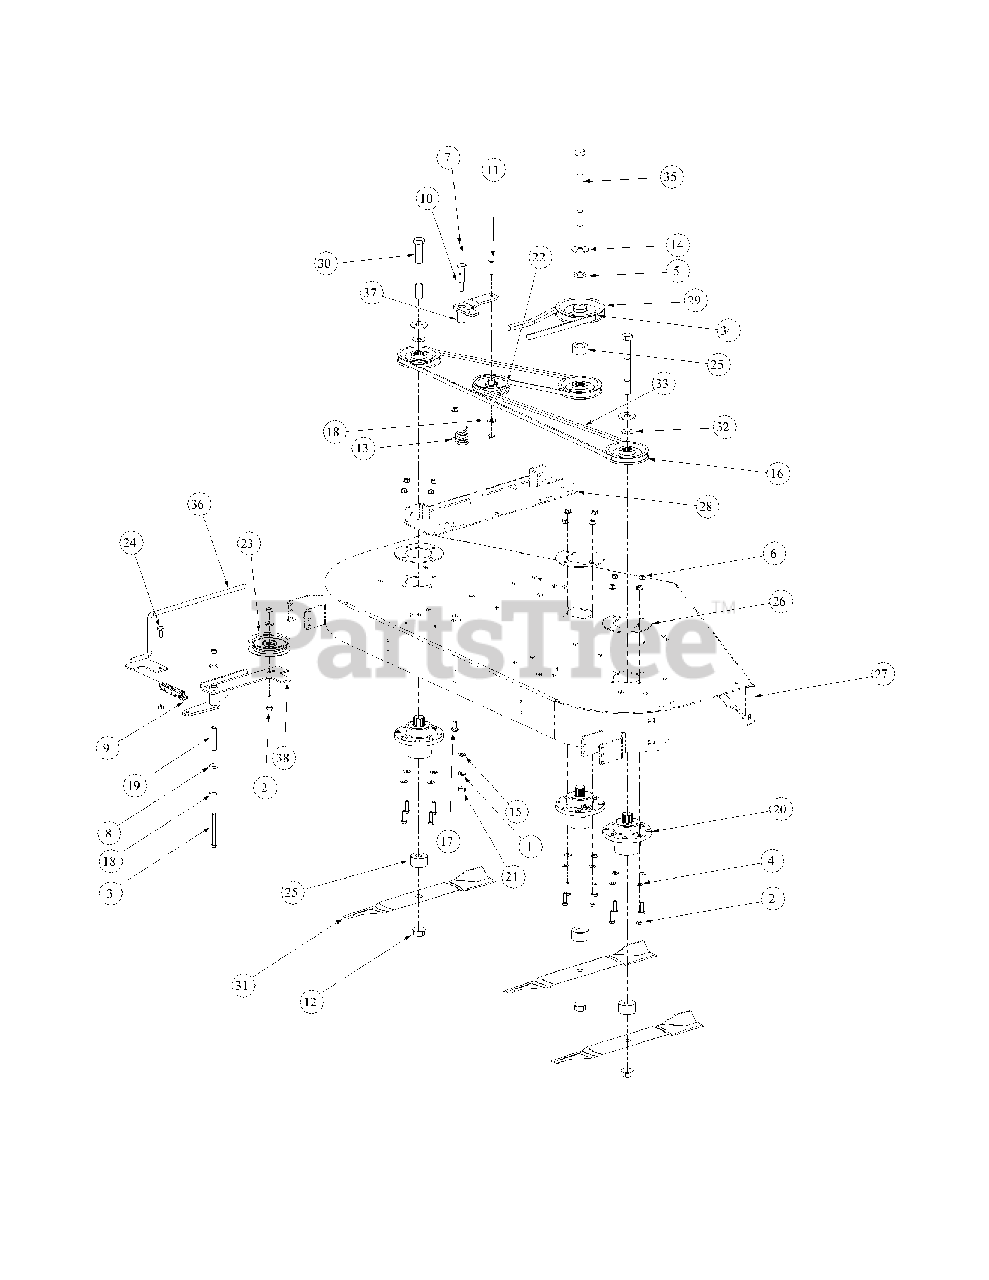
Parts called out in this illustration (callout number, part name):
1	Lock Washer, 7/16
2	Hex Cap Screw, 3/8-16 x 1-1/2
3	Hex Cap Screw, 3/8-16, 4.00
4	Flat Washer, 3/8
5	Caster Spacer
6	Flange Lock Hex Nut, 3/8-16
7	Grease Fitting, 1/4-28 x 3/16
8	Idler Washer
9	Extension Spring, 1.0 x OD x 5.125
10	Shoulder Screw, 7/16-14
11	Hex Carriage Screw, 3/8-16, 1.75
12	Flange Hex Nut, 3/4-16
13	Torsion Idler Spring
14	Flat Washer, .781 ID 2.00 OD, .105
15	Flat Washer, .469 ID, .875 OD, .105
16	V-Pulley, 5.00 OD
17	Carriage Bolt, 3/8-16 x 1
18	Flat Washer, .406 ID, 1.0 OD, .105
19	Spacer, .39 ID x .625 OD x 2.75
20	Aluminum Spindle Assembly
21	Hex Nut, 7/16-14
22	Flat Pulley
23	Idler Pulley, 4.06 OD
24	Shoulder Screw, .50 x .27 Lg., 3/8-16
25	Spacer, .760 ID x 2.00 OD x 1.1
26	Aluminum Spindle Support Plate
27	60 Deck Assembly
28	Left Hand Mount Deck Bracket Assembly
29	V-Pulley, 5.774 OD
30	Hex Cap Screw, 3/4-16, 7.00
31	Hi-Lift Blade, 21.0, 0.756 ID
32	Spacer .812 ID x .268 LG
33	V-Belt, A Section x 122.3
34	V-Belt, B Section x 91.2
35	Hex Cap Screw, 3/4-16, 9.00
36	Spring Tension Rod Assembly
37	Idler Arm Assembly, Deck Spindle
38	Idler Arm Assembly, Flat Top Bearing
